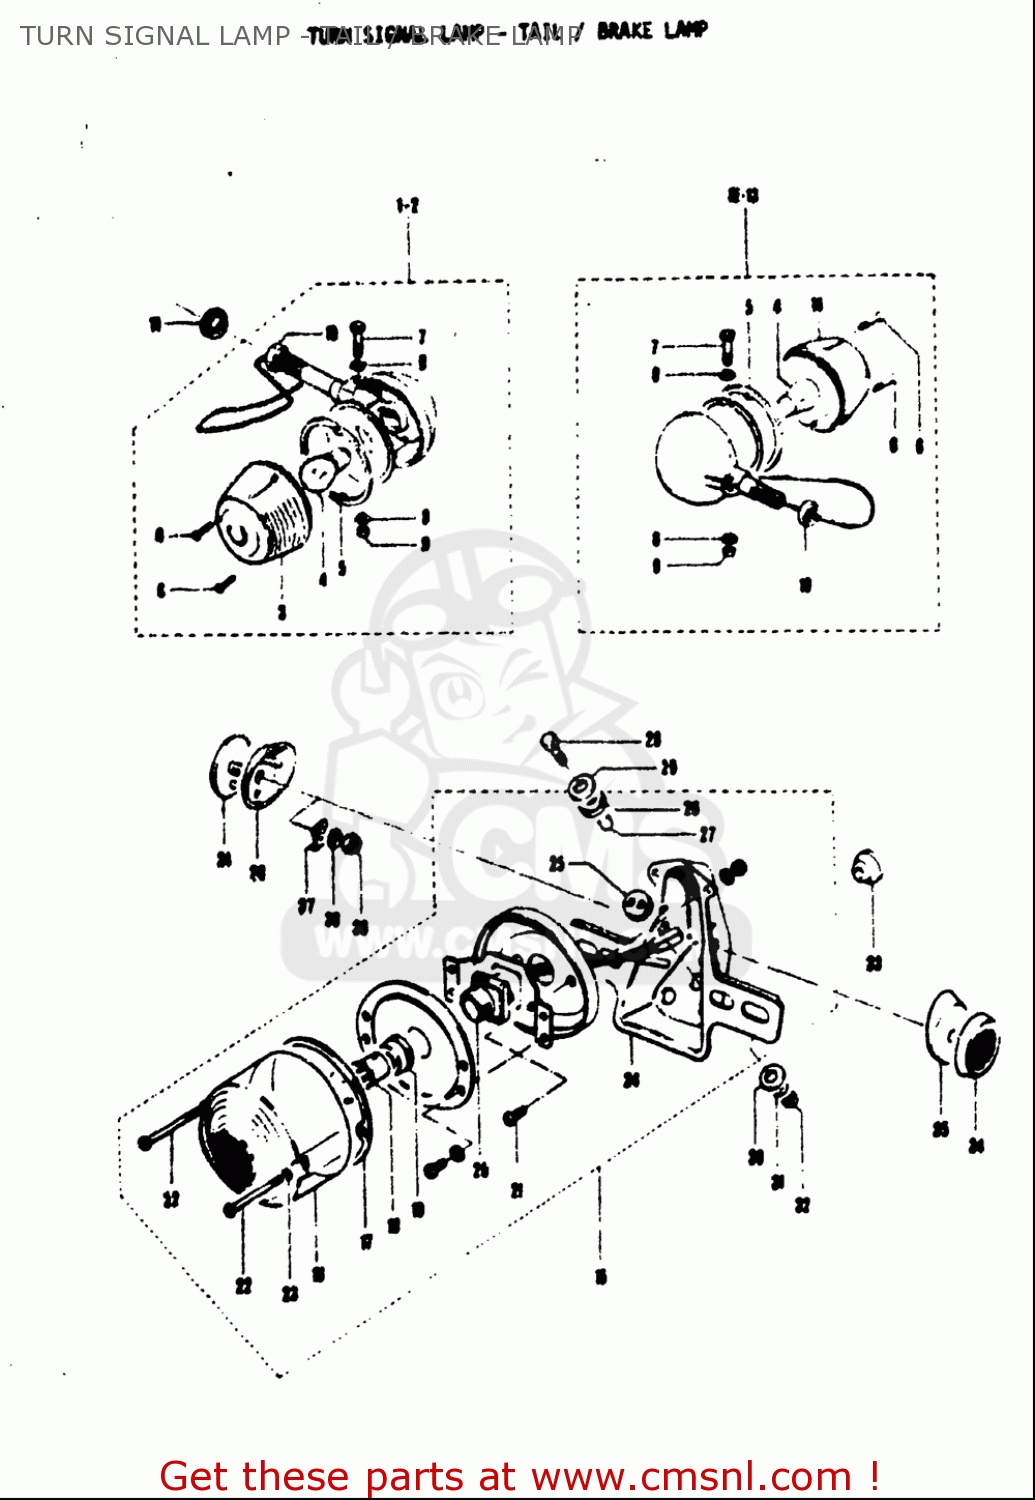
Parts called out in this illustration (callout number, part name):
3	LENS,TURNSIGNAL
4	BULB(6V17W,STANLEY,A4513A)
5	GASKET,TURNSIGNAL LENS (NAS)
8	WASHER
9	NUT
10	NUT
11	WASHER
14	LENS,TURNSIGNAL
16	LENS,RR COMBINATION LAMP
18	BULB(6V17/5.3W,STANLEY,A4813)
25	GROMMET,REAR COMBINATION LAMP
26	CUSHION
27	SPACER
28	BOLT
29	WASHER(6.5X20X1.6)
30	WASHER
31	WASHER,LOCK
32	NUT
38	WASHER,LOCK
39	NUT
